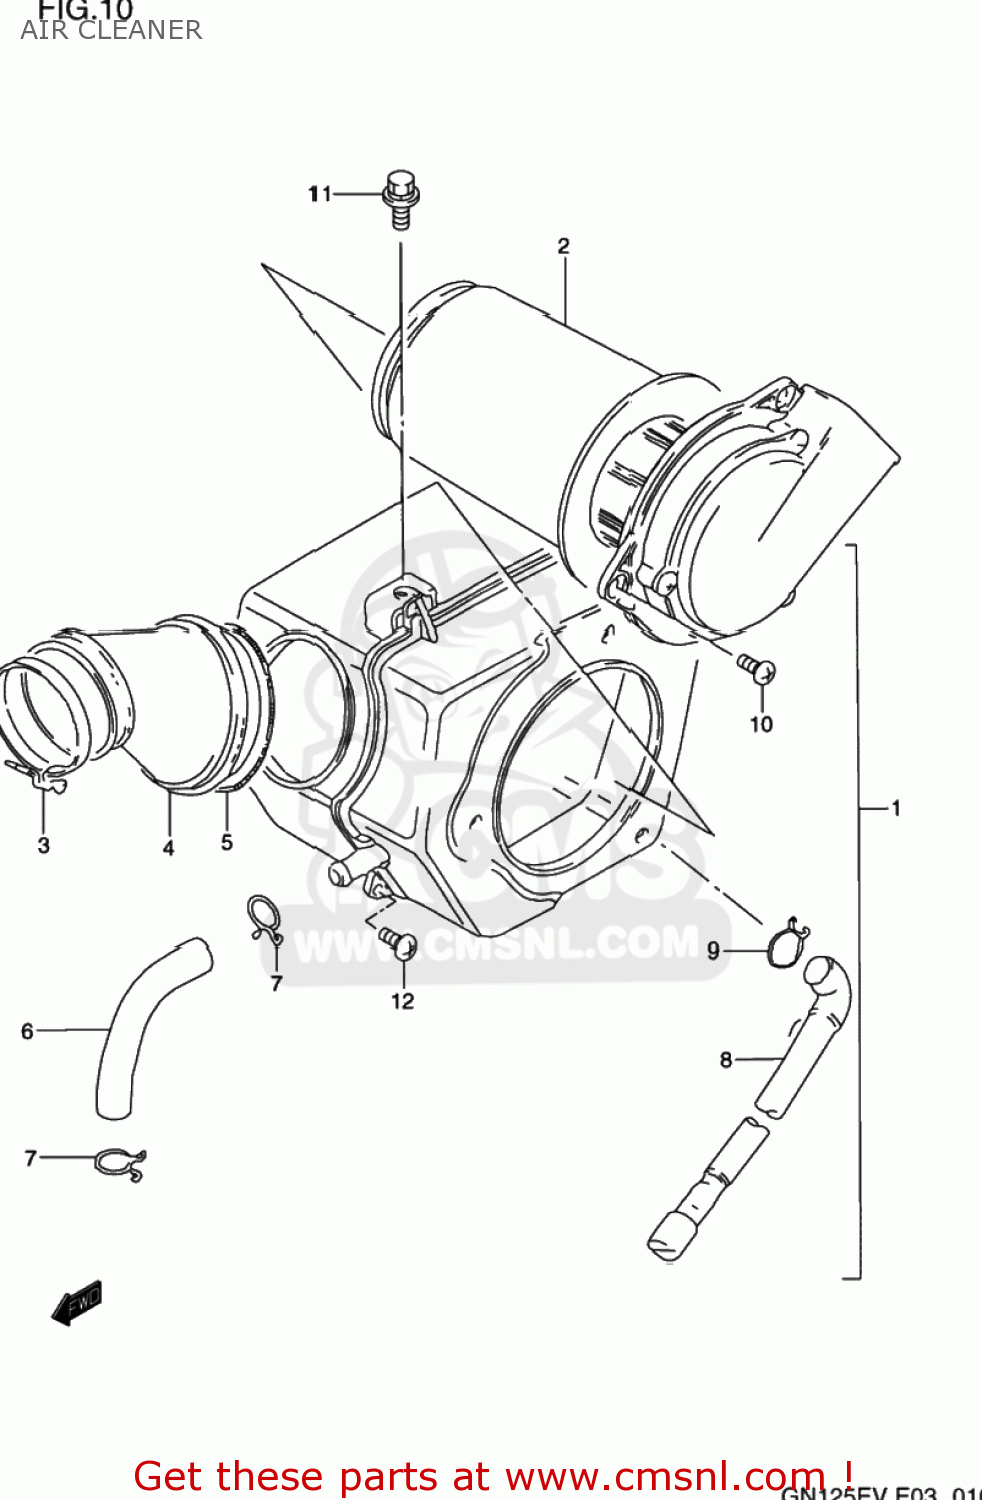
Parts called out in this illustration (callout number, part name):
1	CLEANER ASSY,AIR
2	FILTER
3	CLAMP
4	TUBE,OUTLET
5	CLAMP,AIR CLEANER SIDE
6	TUBE,BREATHER
7	CLIP
8	TUBE,DRAIN
9	CLIP
10	SCREW
11	BOLT
12	SCREW
